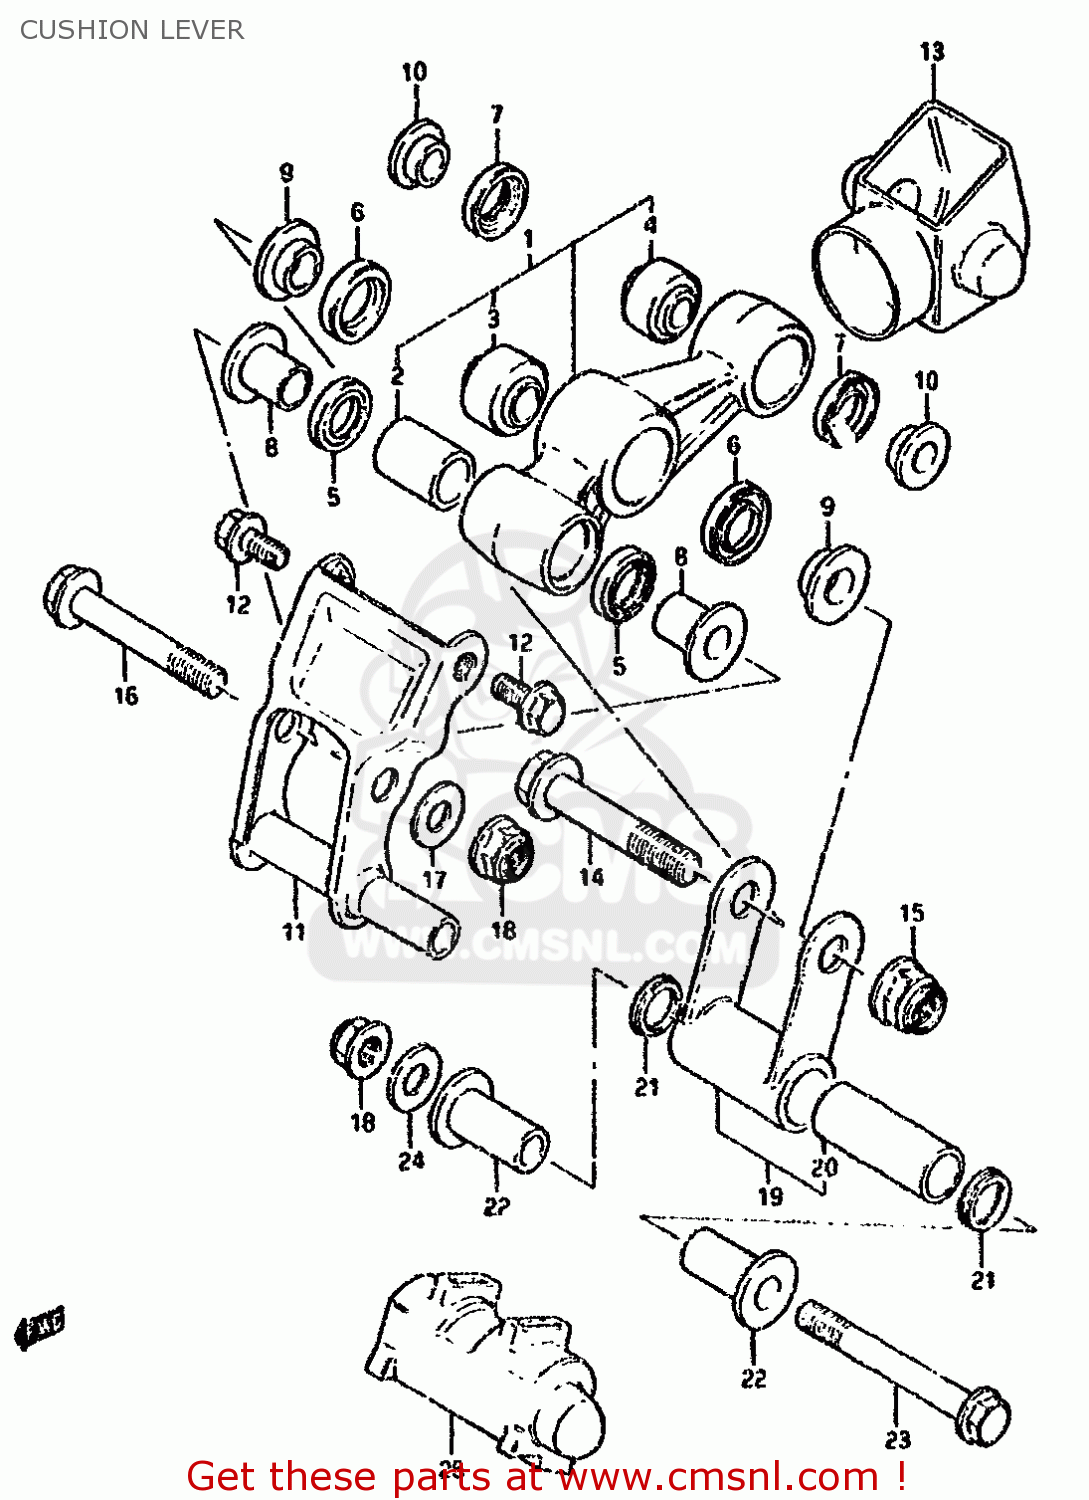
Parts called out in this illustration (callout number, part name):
1	LEVER SET,RR CUSHION
2	BUSHING,CUSHION FR(15X20X31)
3	BEARING(12X26X16)
4	BEARING(10X24X15)
5	DUST SEAL,RR CUSHION LEVER FR
6	DUST SEAL,RR CUSHION LEVER CTR
7	DUST SEAL,RR CUSHION LEVER RR
8	SPACER,RR CUSHION LEVER FR
9	SPACER
10	SPACER
11	HOLDER,RR CUSHION LEVER
12	BOLT,RR CUSHION LEVER HOLDER
13	BOOT,RR
14	BOLT(12X55)
15	NUT 12MM
16	BOLT(10X65)
17	WASHER
18	NUT
19	LOD SET,RR CUSHION
20	BUSHING,LOD LWR(15X20X54)
21	DUST SEAL,LEVER CUSHION UNIT
22	SPACER,RR CUSHION ROD LWR
23	BOLT,RR CUSHION ROD LWR
24	WASHER
25	BOOT,LWR
